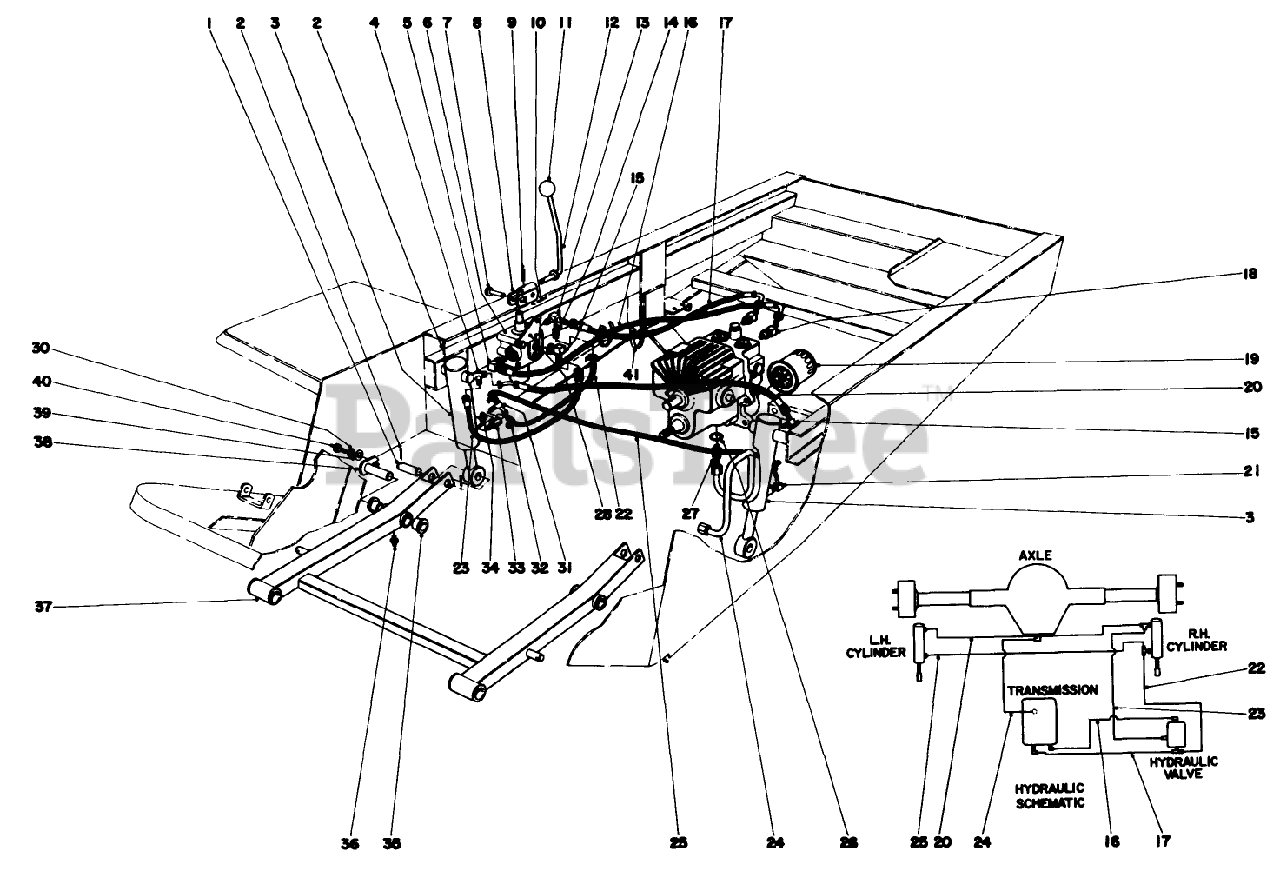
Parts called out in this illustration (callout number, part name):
1	Pin Cylinder
2	PIN-COTTER
3	Lift Cylinder
4	FITTING-TEE, ADJ.
5	FITTING-ELBOW, 90 DEG
6	Valve
7	PIN-CLEVIS
8	Valve Lever Link
9	PIN-ROLL
10	PIN-COTTER
12	Lever-Valve
13	Fitting Assembly
14	FITTING-STRAIGHT
15	FITTING-ELBOW, 90
16	Hose Trans. To Valve Pressure
17	Hose Trans. To Valve Low Pressure
18	FITTING-ELBOW, 45 DEG
19	FILTER-OIL, TRANSMISSION
20	RH CYL HOSE
21	STEM-HOSE
23	RH HOSE
24	HYORAULIC TUBE
25	HOSE-FUEL
26	O-RING
27	FITTING-STRAIGHT
28	Wheel Bolt
30	WASHER-LOCK
31	MALE TEE FITTING
32	CLAMP-HOSE
33	CONN FITTING
34	O-RING
35	7/8 ID X 1.128 X 7/8 LG BSHG
36	GREASE FITTING
37	Lift Arm (Incl. Ref. #35-36)
38	Pin-Pivot
39	WASHER-FLAT
40	SCREW-HH
41	TIE-CABLE
